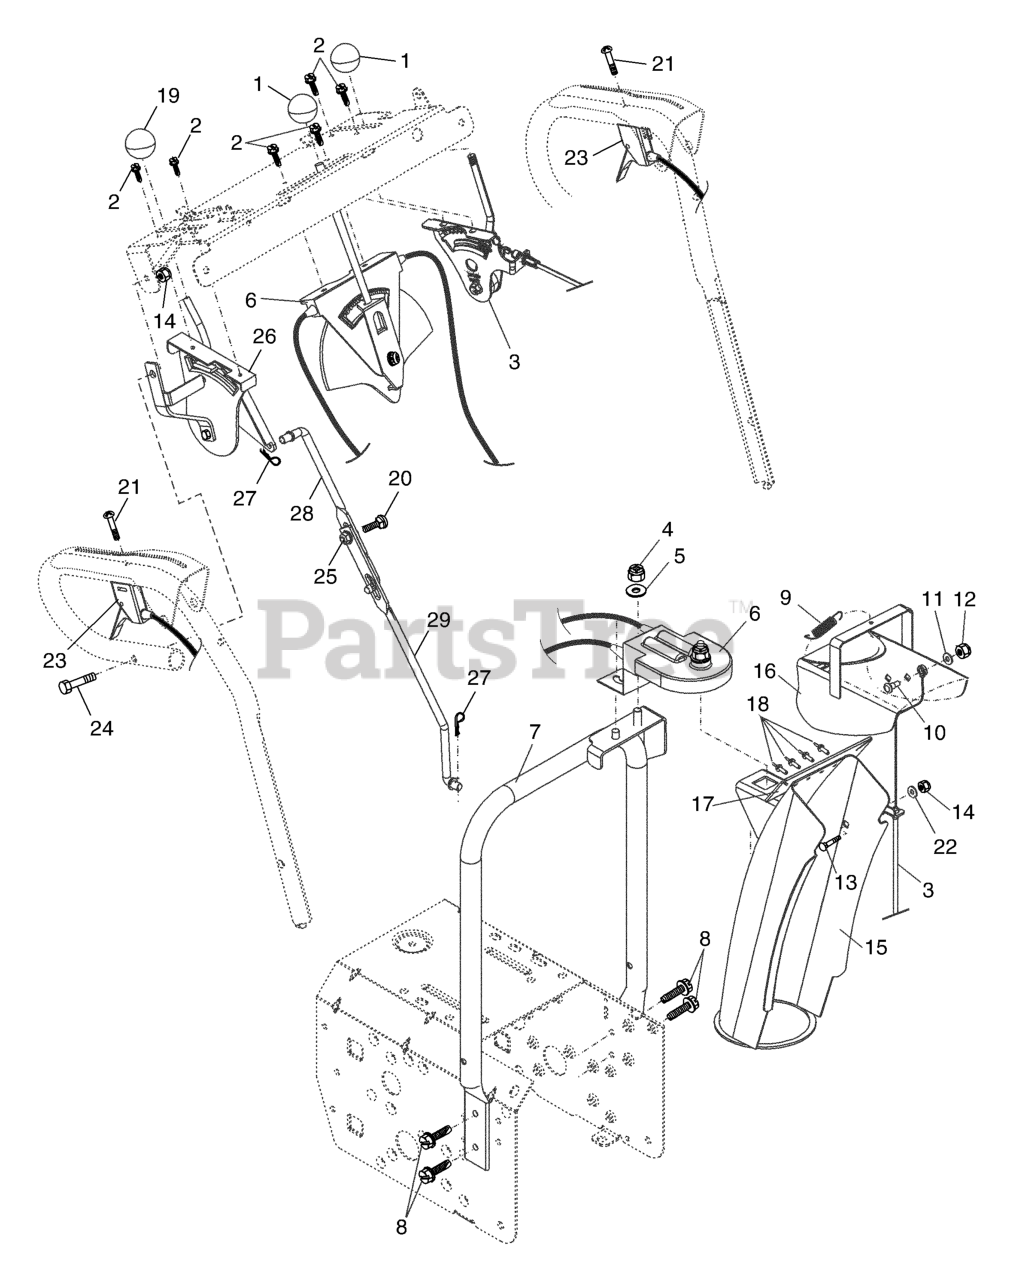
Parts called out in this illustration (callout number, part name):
1	KNOB, LEVER
2	SCREW #10-24 X 5/8
3	CONTROL ASSY, DEFLECTOR
4	NUT
5	WASHER
6	CONTROL ASSY, CHUTE ROTATER
7	SUPPORT CHUTE ROTATER
8	SELF-TAPPING SCREW 5/16-18X3/4
9	SPRING.DEFLECTOR.REM.CHUTE
10	BOLT, SHOULDER
11	WASHER
12	LOCKNUT.NYLOC.1/4-20
13	BOLT
14	NUT.71038.31-18.HEX.NYLOCK
15	CHUTE ASSY
16	DEFLECTOR.WELDMENT.PNT.ORANGE
17	SEAL, DEFLECTOR
18	RIVET BLIND
19	RP KNOB, SPEED CONTROL LEVER
20	BOLT
22	WASHER.20X8.5
23	CONTROL ASSY, POWER STEERING
25	NUT.FLANGE.5/16
26	LEVER ASSEMBLY, SPEED CONTROL
27	SPRING RETAINER
28	ROD, UPPER SPEED CONTROL
29	ROD, LOWER SPEED CONTROL.SNOW
